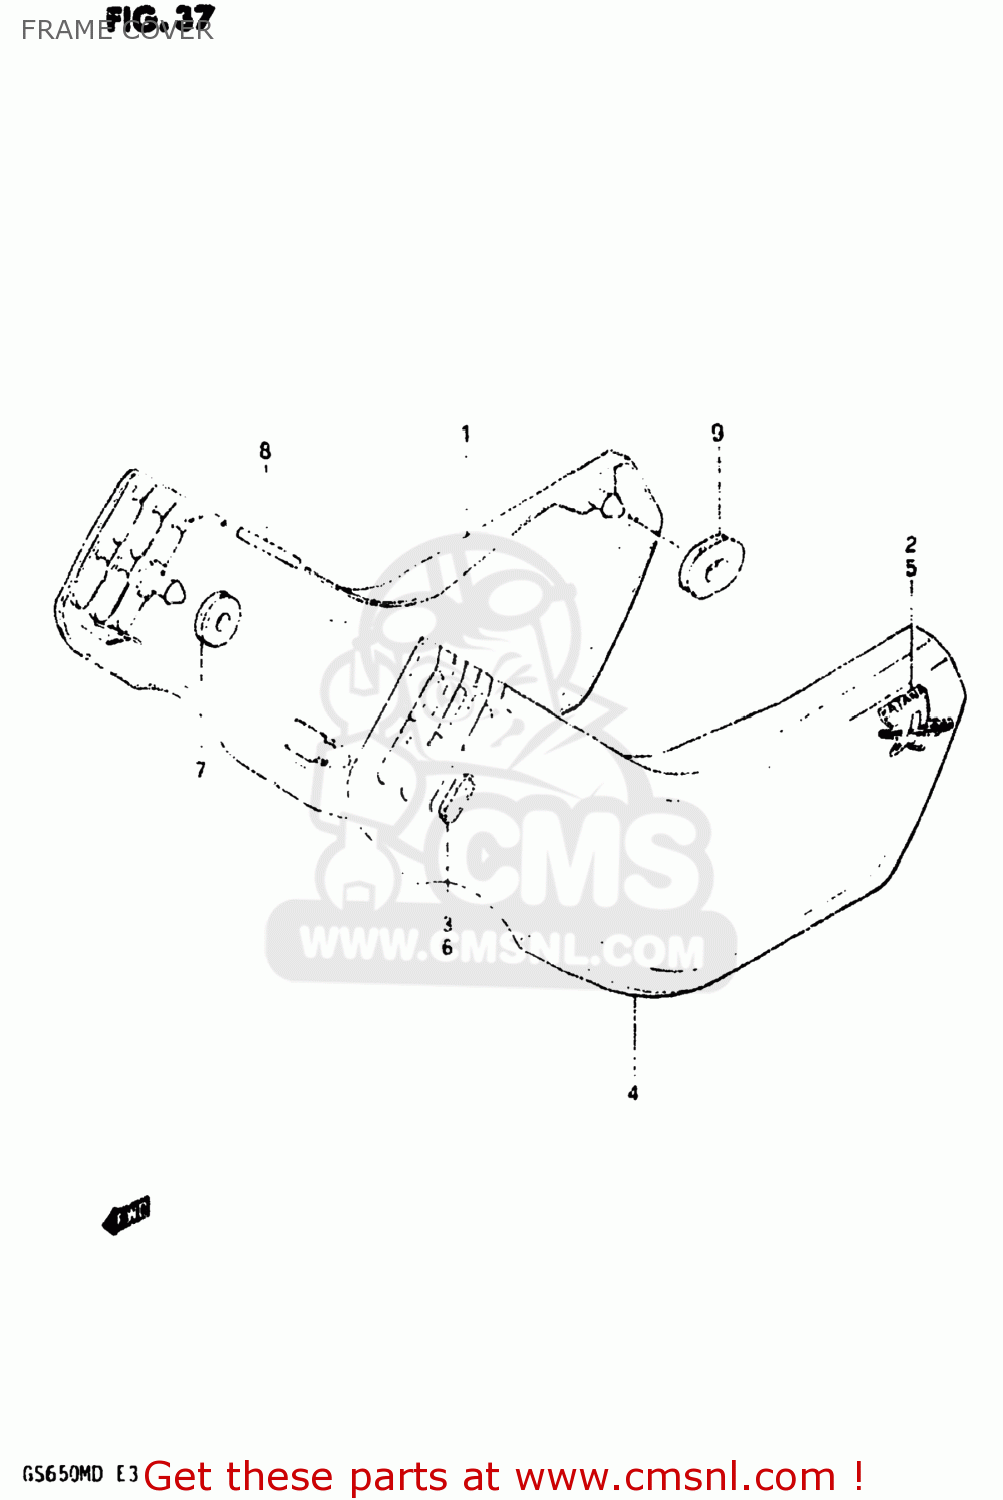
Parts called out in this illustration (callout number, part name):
1	COVER,FRAME,RIGHT
2	EMBLEM (KATANA)
3	EMBLEM,FRAME COVER
4	COVER,FRAME,LEFT
5	EMBLEM (KATANA)
6	EMBLEM,FRAME COVER
7	CUSHION
8	CUSHION
9	CUSHION
